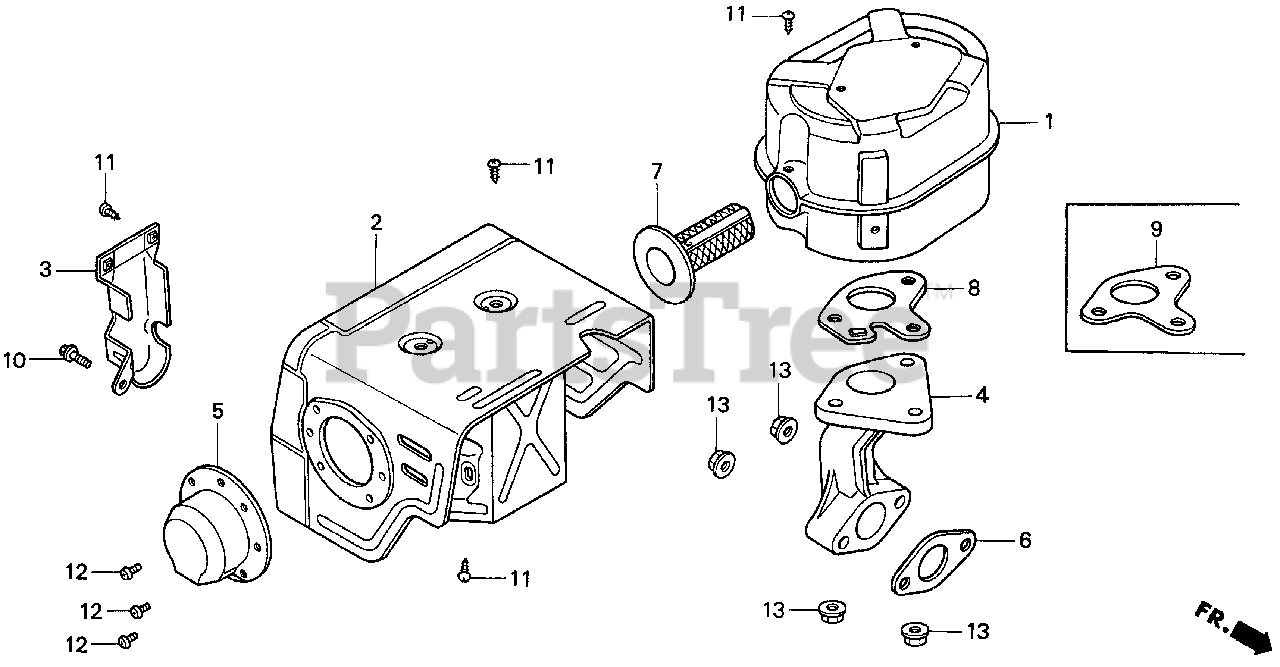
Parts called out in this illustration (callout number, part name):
1	MUFFLER
2	PROTECTOR, MUFFLER
3	PROTECTOR, EX. PIPE
4	PIPE, EX.
5	CAP, MUFFLER
6	GASKET, EX. PIPE
6	GASKET, EX. PIPE (WACKER)
7	ARRESTER, SPARK
8	GASKET, MUFFLER (ARRESTER)
10	BOLT, FLANGE (6X12) (CT200)
11	SCREW, TAPPING (5X8)
12	SCREW, TAPPING (4X6)
13	NUT, FLANGE (8MM)
